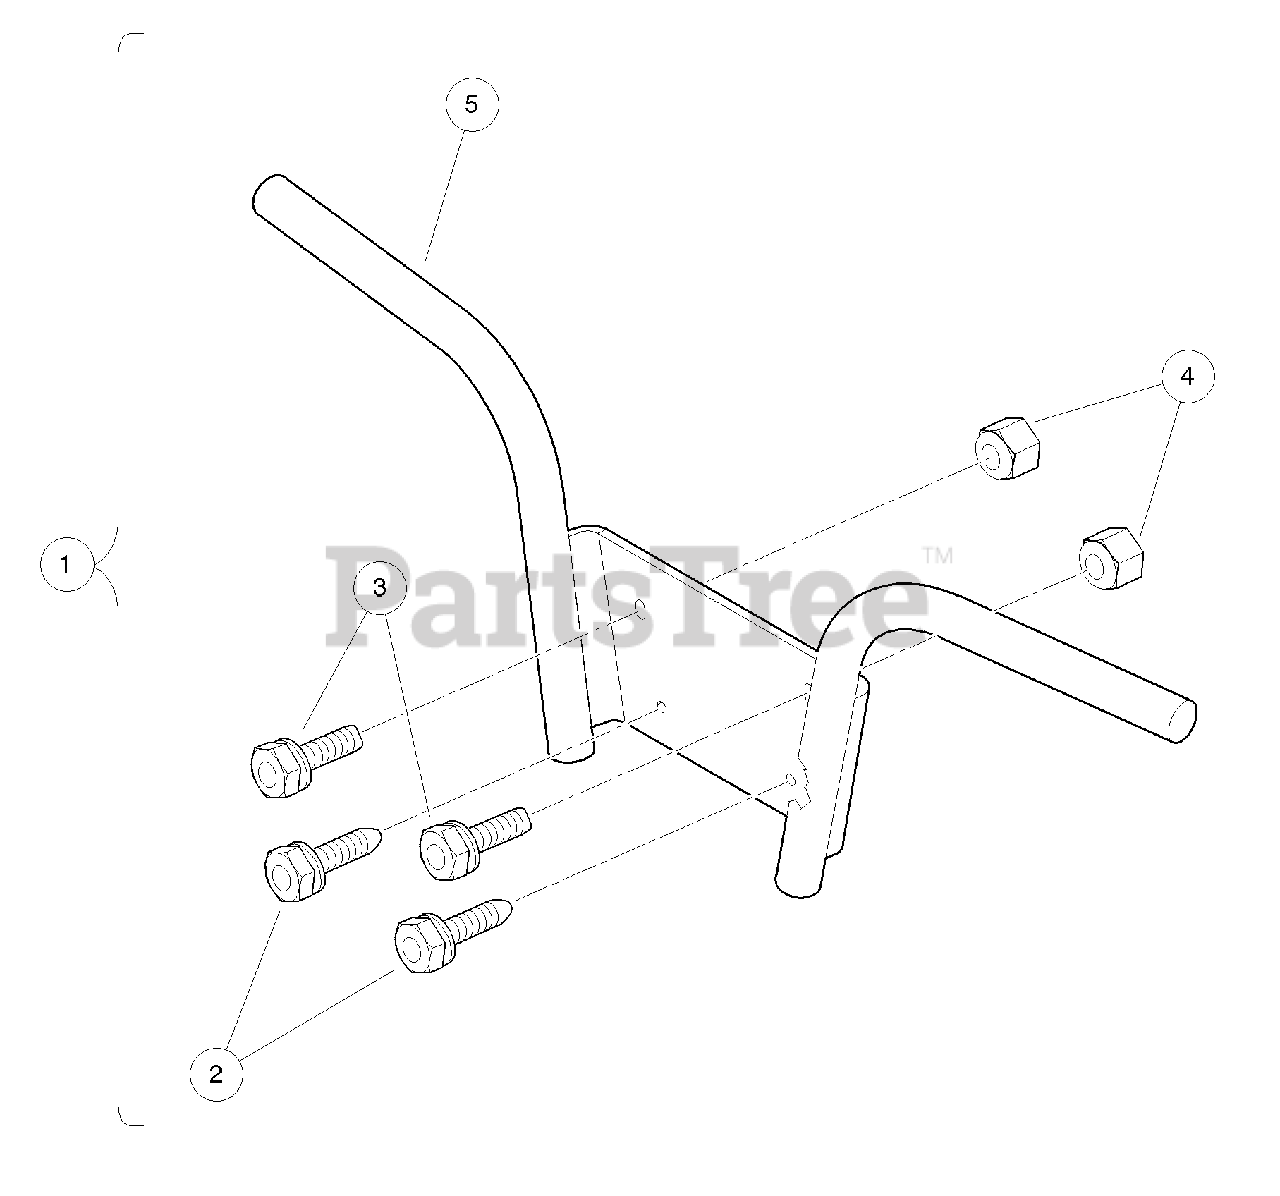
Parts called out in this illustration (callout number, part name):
1	Kit, Brush Guard
2	Screw, M8 X 1.25 X 30 Tri, Blk
3	Bolt, Flange Head, M8-1.25 X 40
4	Lock Nut, Flg M8 X 1.25 Nylon
5	Guard, Brush
6	Instr, Brush Guard
